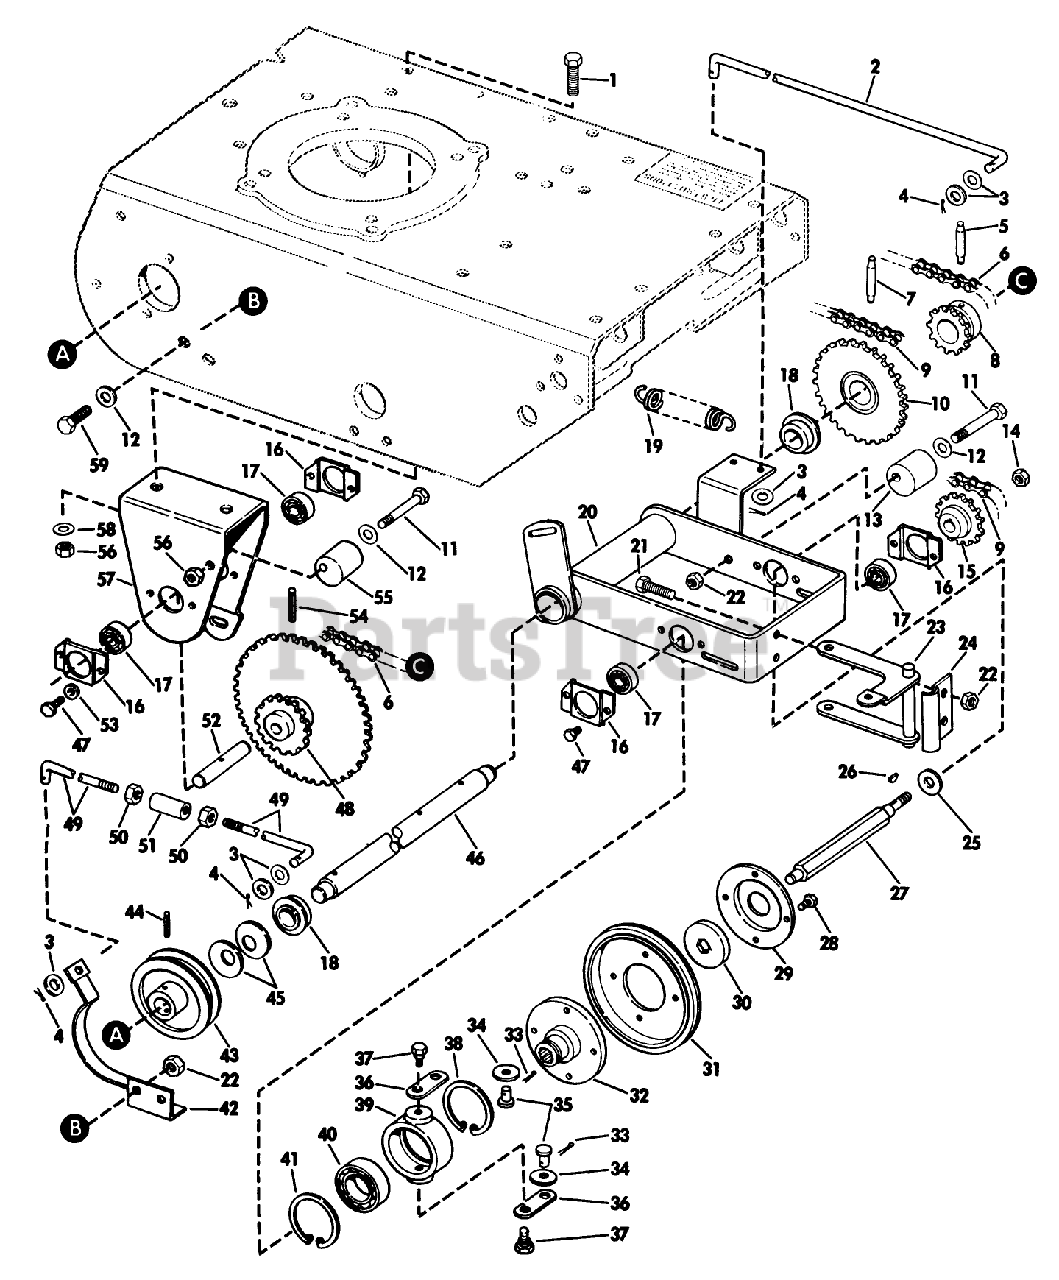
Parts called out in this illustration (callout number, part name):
14	LOCKNUT
31	DRIVE WHEEL
50	STOP NUT
56	LOCKNUT
